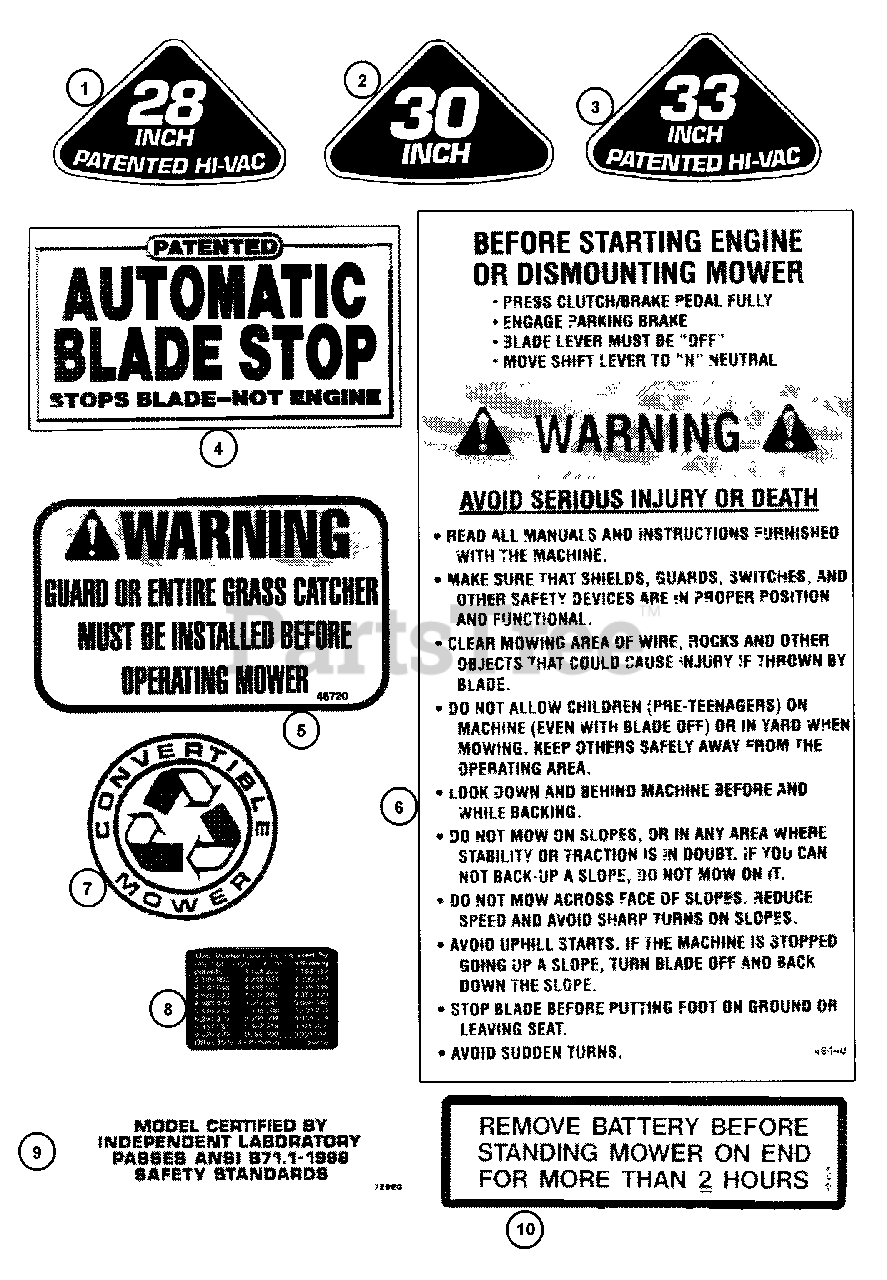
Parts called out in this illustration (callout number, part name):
1	DECAL, 28 Inch
2	DECAL, 30 Inch
3	DECAL, 33 Inch
4	DECAL, Auto Blade Stop
5	DECAL, Chute/Deflector Warning
6	DECAL, Safety Instructions
7	LOGO, Convertible Mower (Blue)
8	DECAL, Patent Numbers
9	DECAL, Certification, B71.1-1998
10	DECAL, Battery
